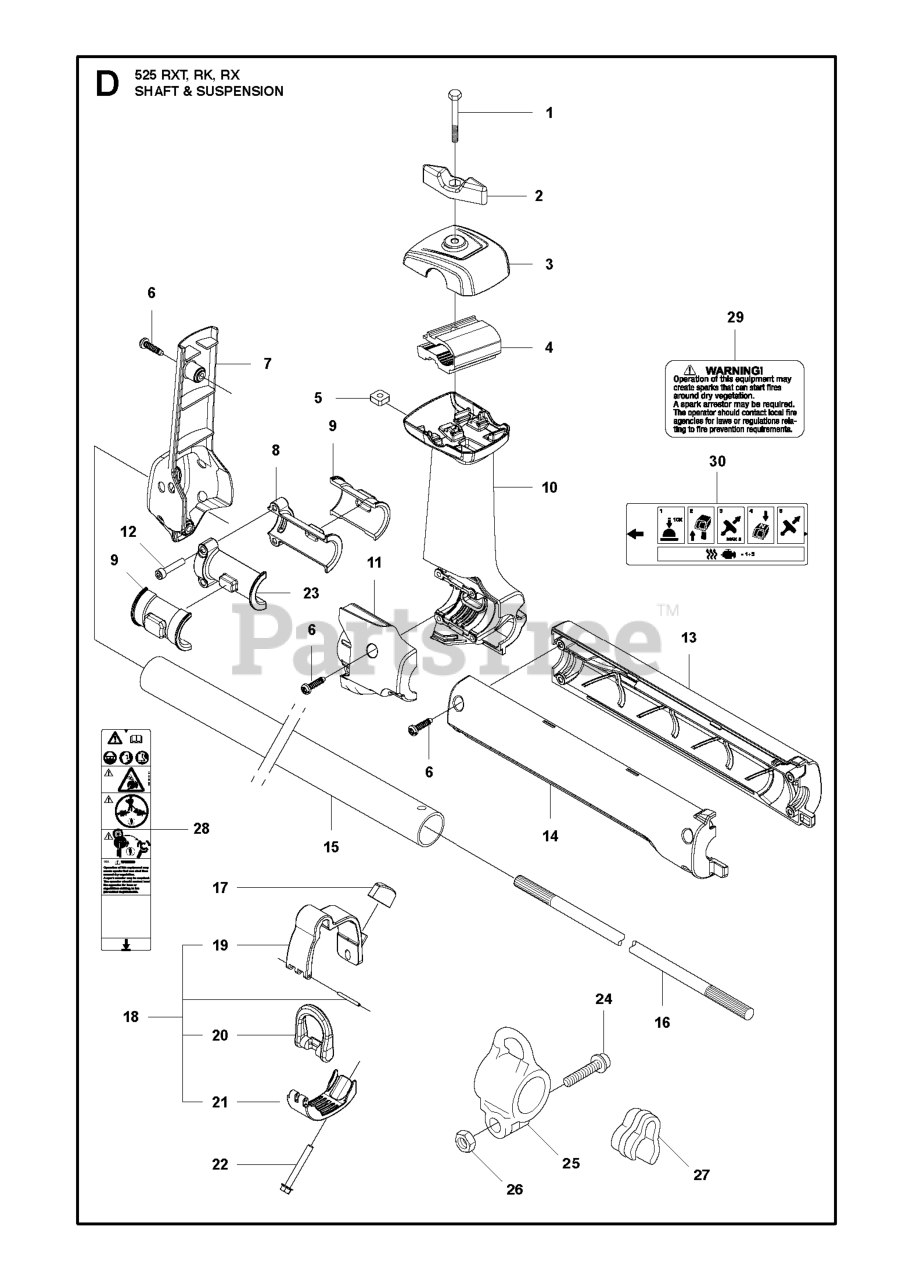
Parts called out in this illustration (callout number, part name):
1	%SCREW
6	SCREW ITXSCT MT5X20 T27 12.9
7	COVER TOWER
8	BRACKET (A)
9	ABSORBER
9	Spacers
10	HANDLE BAR BRACKET COMP
11	COVER HANDLEBAR BRACKET
13	WEAR PROTECTION RIGHT
14	WEAR PROTECTION LEFT
15	TUBE COMP
16	DRIVESHAFT
17	KNOB
18	Loop
19	CLAMP UPPER
20	HOOK
21	CLAMP LOWER
22	SCREW M6S 5X40
23	BRACKET (B)
24	SCREW
25	HARNESS HOLDER
26	NUT
27	GROMMET
28	LABEL WARNING TRIMMERS AND BRU
29	DECAL SPARK ARRESTOR WARNING
30	DECAL START REMINDER 523/525
